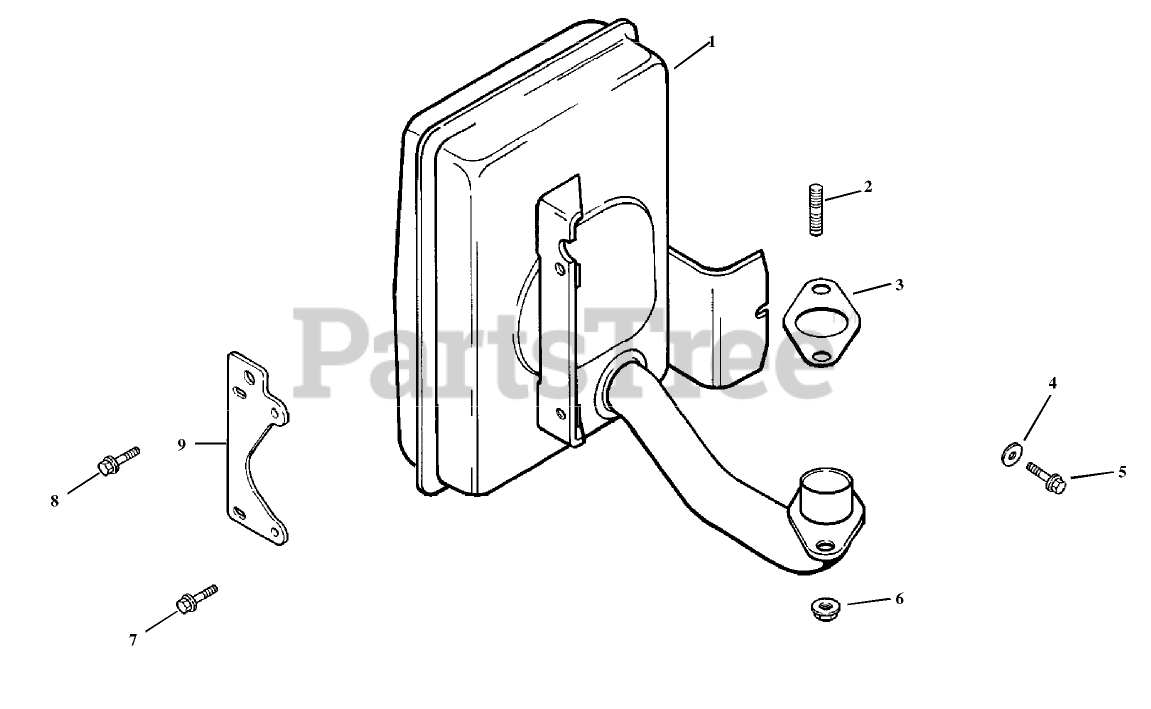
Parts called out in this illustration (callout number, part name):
1	Muffler
2	STUD (M8X1.25X33)
3	Gasket-Manifold, Exhaust
4	Washer-Plain (1/4in)
5	SCREW-FLANGE, THREAD FORMING (M5X0.8X16)
6	NUT-FLANGE (M8X1.25)
7	SCREW-FLANGE, THREAD FORMING (M6X1.0X16)
8	SCREW-FLANGE, THREAD FORMING (M6X1.0X25)
9	Bracket-Muffler
